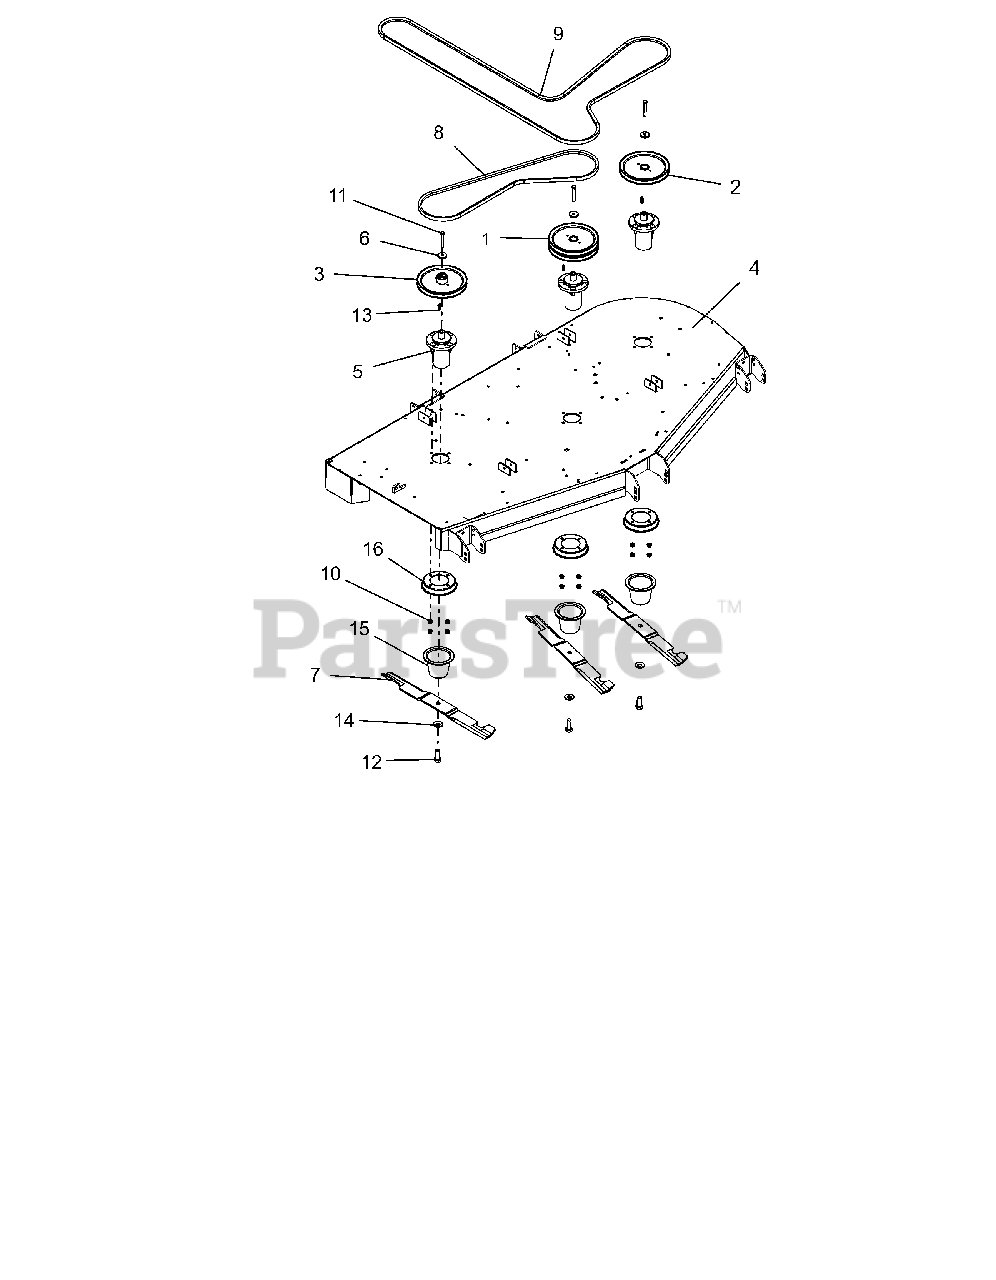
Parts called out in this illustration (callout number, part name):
1	SHEAVE-DOUBLE 1.00"IDX8.25"OD
2	SHEAVE-SINGLE 1.00"IDX8.25"OD
3	SHV-SINGLE 1.00"ID X 8.25"OD
4	72"SIDE DISCH DECK WMT W/SAFE
5	ASM, MAINT FREE ALUM SPINDLE
6	RETAINER, SHEAVE
7	BLADE, 72"
8	V-BELT, B-COGGED
9	V-BELT, HB WRAPPED
10	NUT-LK-CTR-FLG .38-16 YWZC
11	BLT-HEX .38-16X2.75 GR8 YWZC
12	BLT-HEX .62-18X1.75 GR8 YWZC
13	KEY, SQ .25X.25X1.00 RC 40-50
14	WSHR-BLVL .669X1.535X.138
15	GUARD, SPINDLE LOWER
16	GUARD, SPINDLE TOP
